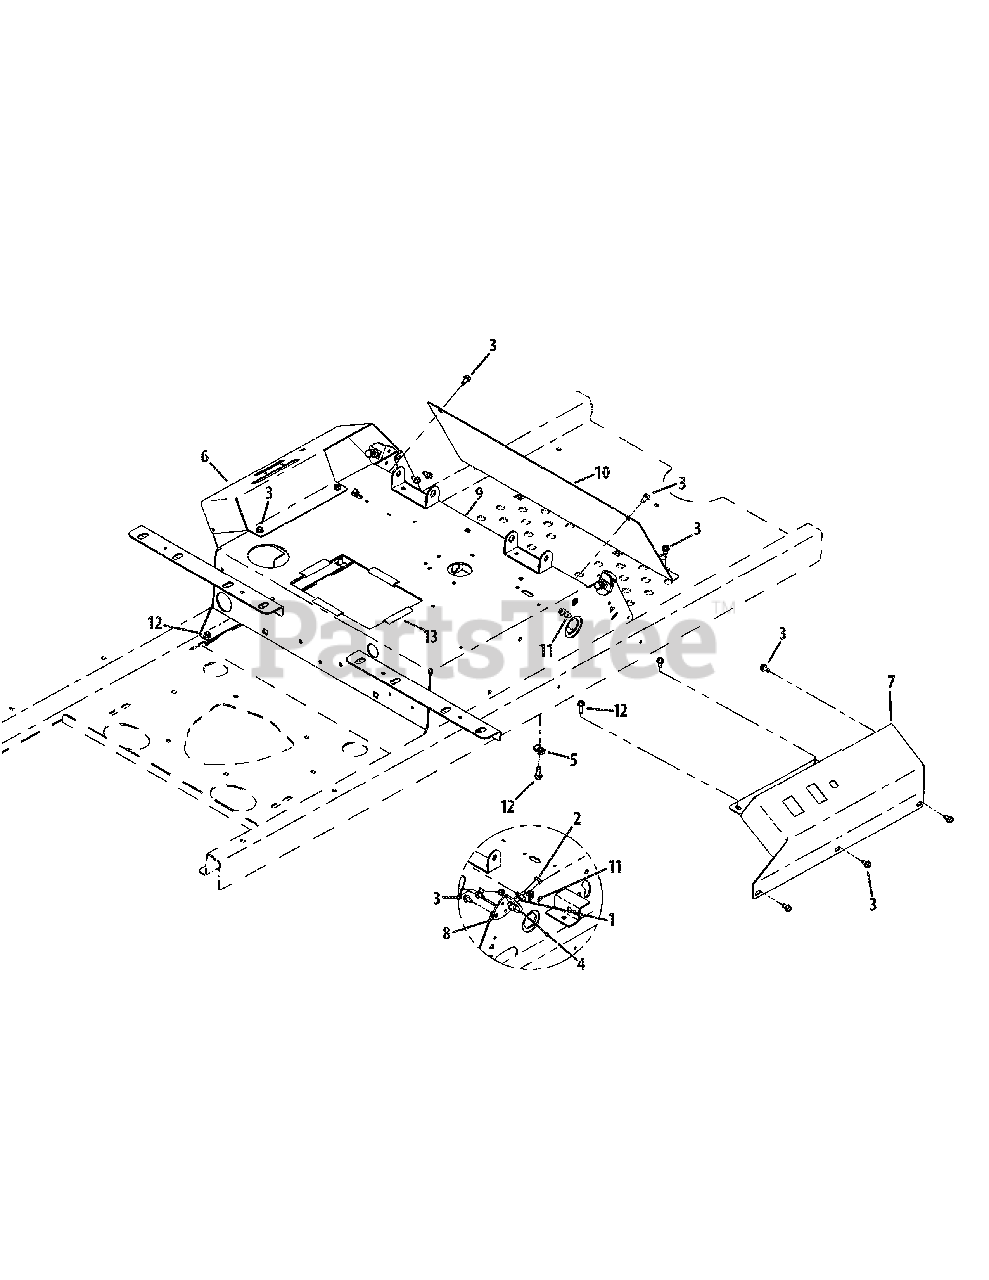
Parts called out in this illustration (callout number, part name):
1	Hex Nut, 5/16-18
2	HHCS, 5/16-18 x 1-1.4
3	Screw, 1/4-20 x 1/2
4	U-Nut, 5/16-18
5	U-Nut, 1/4-20
6	Left Hand Control Console
7	Right Hand Control Console
8	Forward/Reverse Stop Bracket
9	Control Housing Weldment
11	Self-Tapping Screw 5/16-18 x .750
12	Self-Tapping Screw, 1/4-20 x .75
13	Battery Edge Trim
